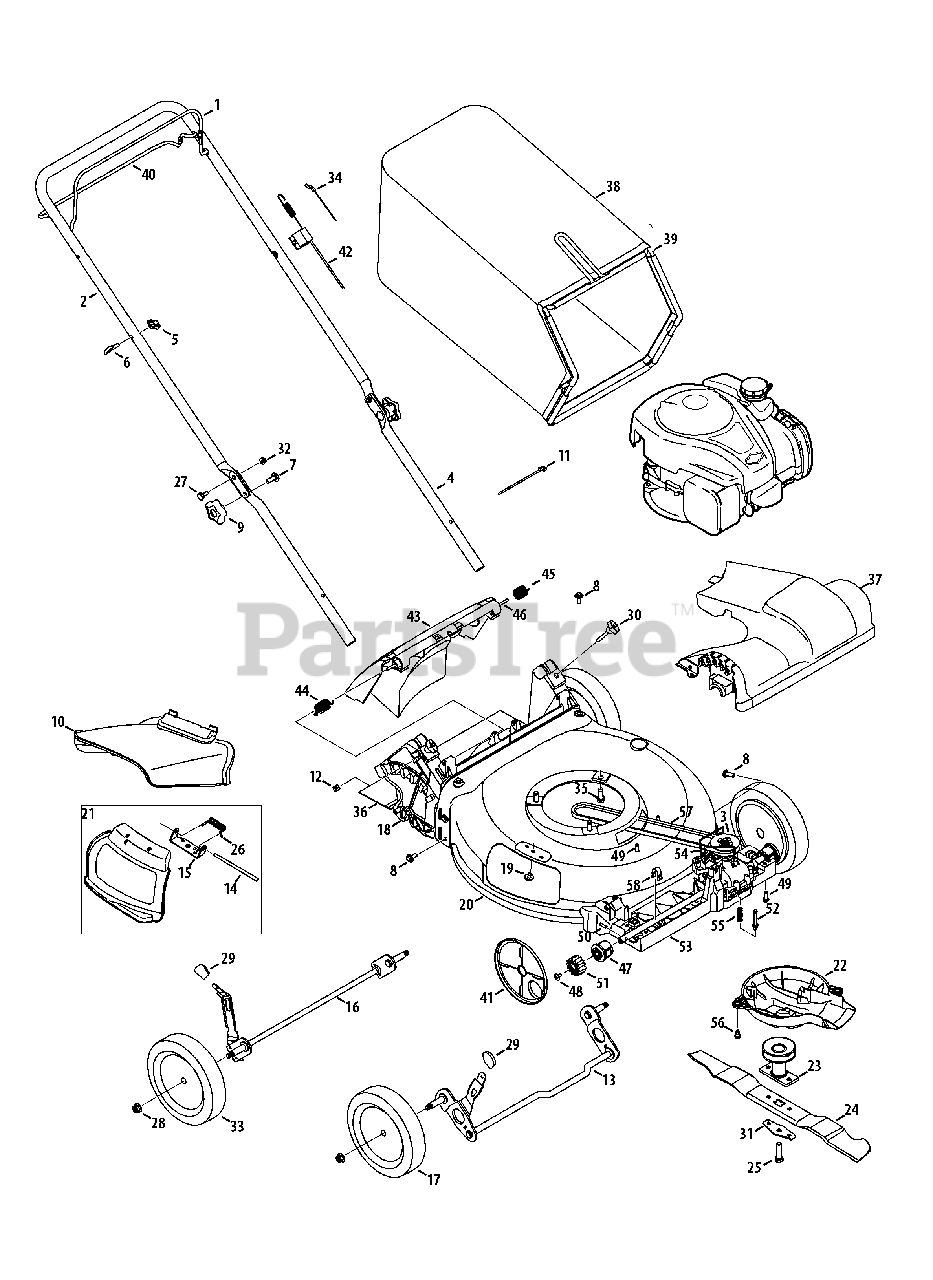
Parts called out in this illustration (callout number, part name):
1	Blade Control
2	Upper Handle
3	Transmission
4	Lower Handle
5	Wing Nut
6	Rope Guide
7	Carriage Screw ,5/16-18
8	Screw, 5/16-14 x .750
9	Hand Knob
10	Side Chute
11	Cable Tie
12	Nut, Sq., 1/4-20
13	Front Axle Assembly
14	Hinge Pin
15	Chute Deflector Bracket
16	Rear Axle Assembly
17	Wheel, 8 x 1.8
18	Rear Baffle
19	Screw, 1/4-20 x .500
20	Deck - 21"
21	Hinged Mulch Plug Assembly
22	Engine Baffle
23	Blade Adapter
24	Mulching Blade
25	Screw , 3/8-24 x 1.50
26	Torsion Spring
27	Sldr. Screw, .375 x .126 x 1/4-20
28	Flange Lock Nut, 3/8-16
29	Adjustment Lever Knob
30	Wing Nut
31	Blade Bell Support
32	Nut, Flange Lock, 1/4-20
33	Wheel, 8 x 1.8
34	Control Cable
35	TT Screw, 3/8-16 x 1.0
36	Trail shield
37	Front Cover
38	Grass Bag
40	Drive Control
41	Dust Cover
42	Drive Cable
43	Rear Door
44	Torsion Spring - RH
45	Torsion Spring - LH
46	Pivot Rod
47	Bearing Assembly
48	Screw, 1/4-20 x .390
49	Screw, 1/4-15 x .750
51	Spur Gear - RH
51	Spur Gear - LH
52	Body, Spr.
53	Lower Tray
54	Wire
55	Compression Spring
56	Screw, Shldr., 1/4-20 x .50
